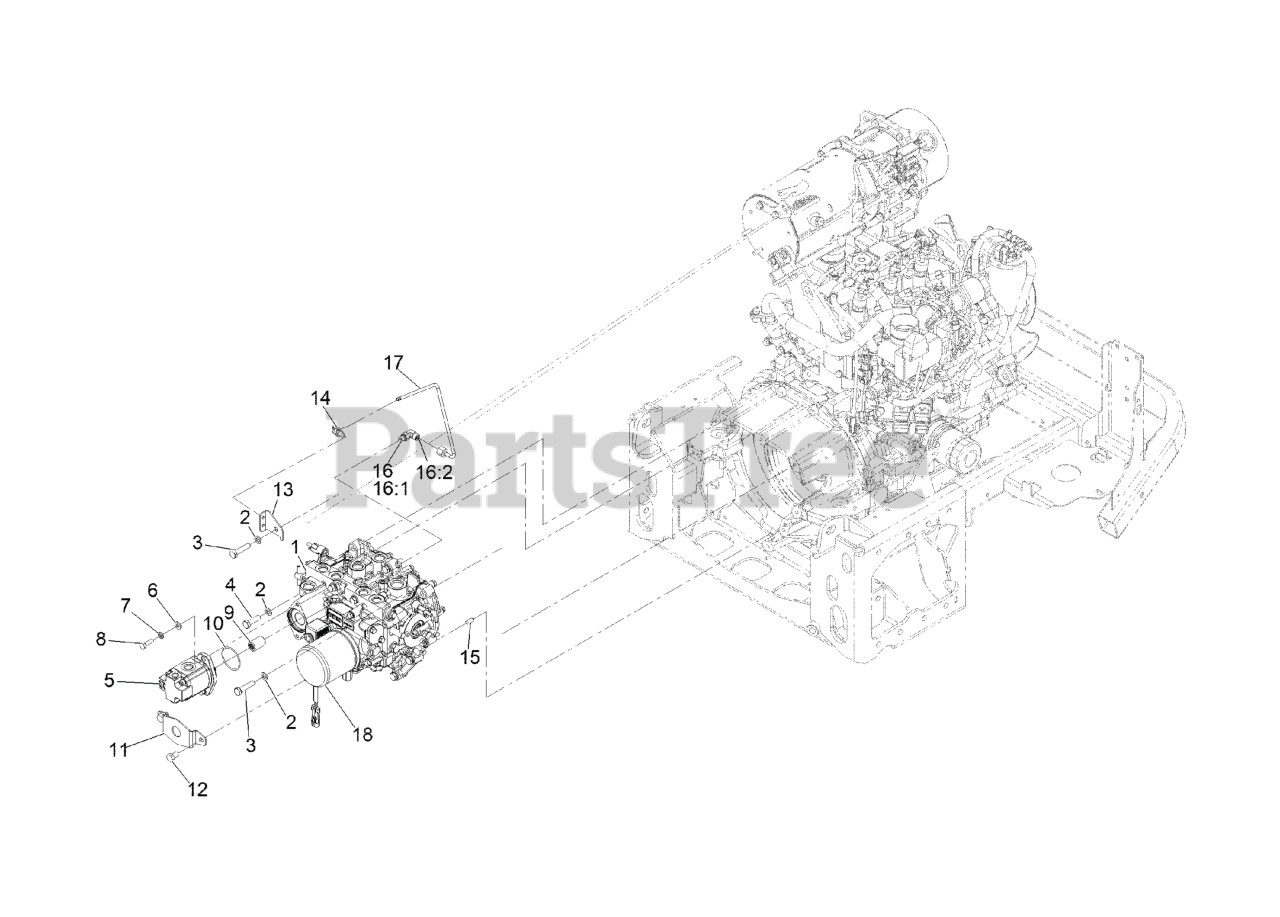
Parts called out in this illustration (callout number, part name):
1	TRANSMISSON ASM
2	WASHER-LOCK
3	SCREW-HH
4	SCREW-HH
5	HYD GEAR PUMP ASM
6	WASHER-PLAIN
7	WASHER-LOCK
8	SCREW-HH
9	COUPLER-SPLINE
11	SHIELD-SEAL
12	SCREW-HH
13	SUPPORT-TUBE
14	CLIP-TIE
15	PIN-DOWEL
16	FITTING-ELBOW, 90 DEG
16:1	O-RING
16:2	O-RING
17	TUBE ASM
18	FILTER-OIL, HYD
